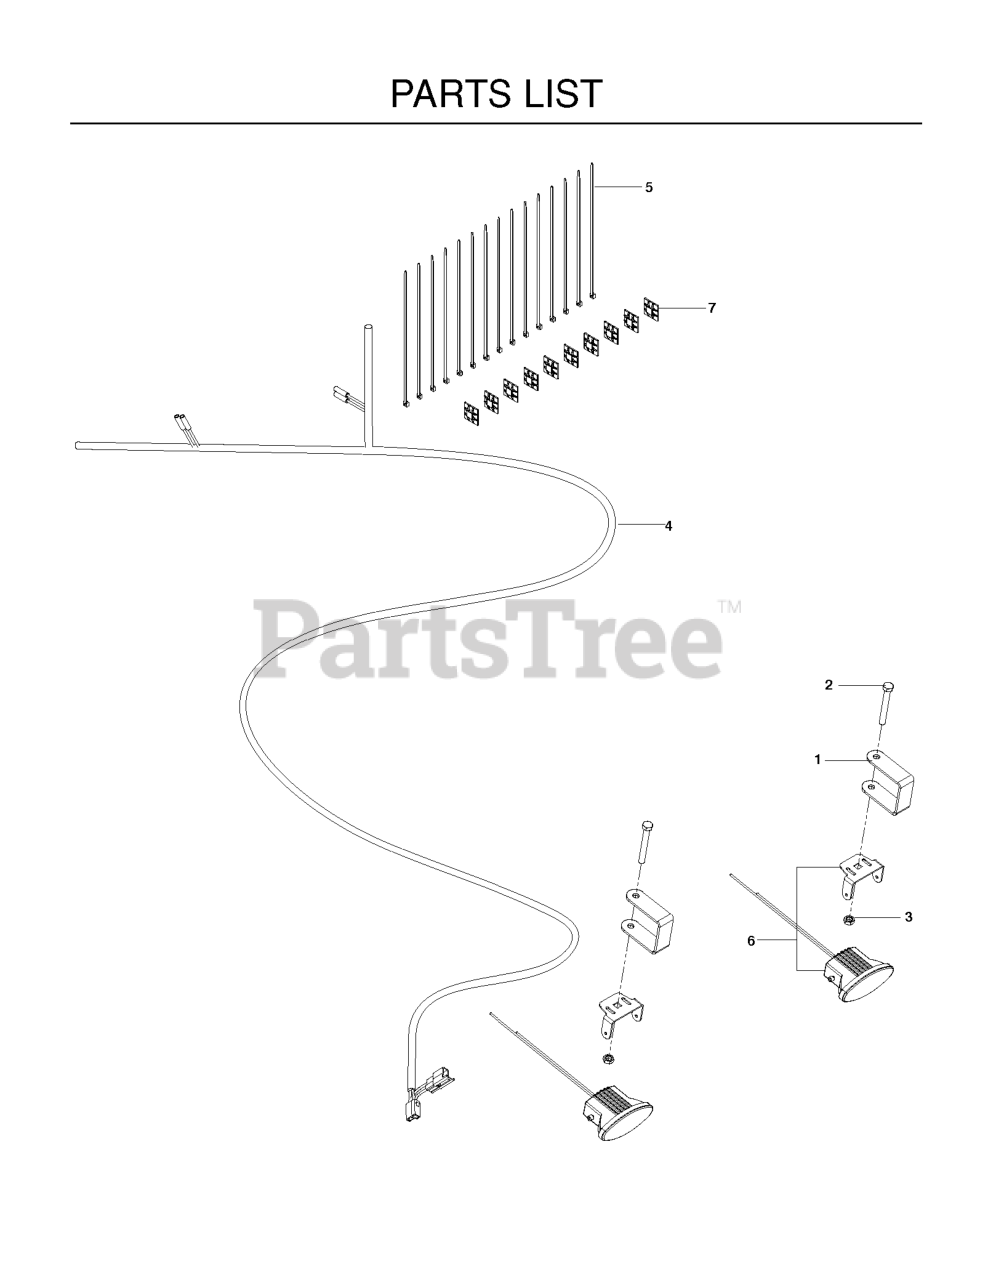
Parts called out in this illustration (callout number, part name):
1	BRACKET, LIGHT MOUNT GRAY
2	BOLT 5/16C X 2 1/2
3	NUT 5/16-18 HEX JAM ZD
4	HARNESS LIGHT KIT
5	TIE, PLASTIC
6	LIGHT 35W W/BRKT
7	MOUNTING BLOCK CABLE TIE
